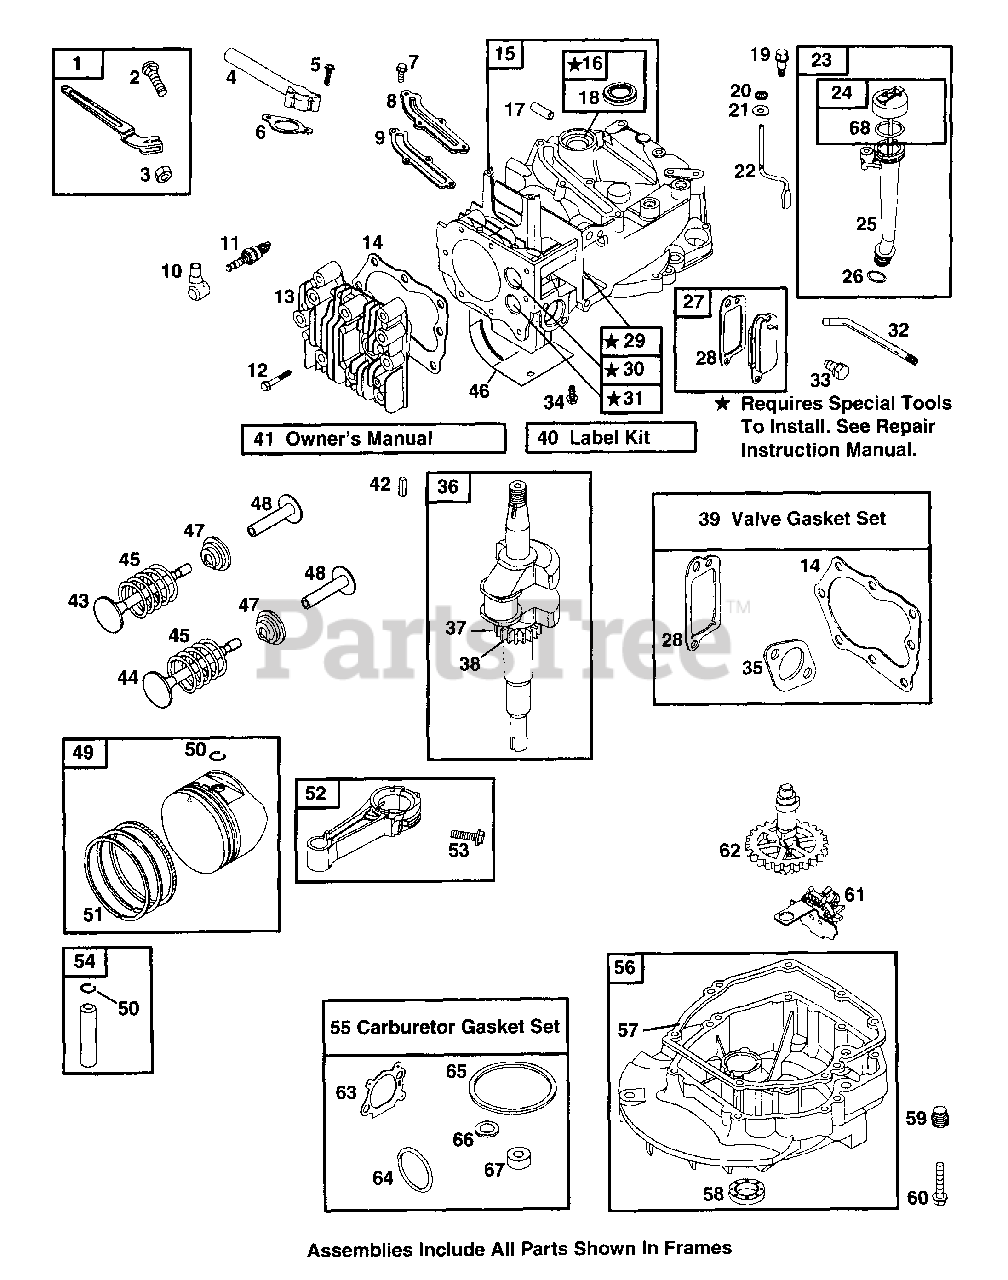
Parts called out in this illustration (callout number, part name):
1	Governor Control Lever
4	Intake Manifold
6	Intake Gasket
8	Breather Passage Cover
9	Breather Passage Gasket
10	Sparkplug Boot
12	Screw (Cylinder Head)
13	Cylinder Head
14	Cylinder Head Gasket
15	Cylinder Assembly
16	Bushing/Seal Kit
17	Locating Pin
18	Oil Seal (Magneto Side)
20	Governor Shaft Retainer
22	Governor Crank
23	Dipstick/Tube Assembly
24	Dipstick
25	Dipstick Tube
26	Dipstick Tube Seal
27	Oil Seal
28	Breather Gasket
29	Guide Bushing (Exhaust Valve)
30	Valve Seat (Intake)
31	Valve Seat (Exhaust)
32	Breather Tube
35	Exhaust Gasket
36	Crankshaft Assembly
37	Timing Key
38	Timing Gear
39	Valve Gasket Set
41	Owner's Manual
42	Flywheel Key
43	Intake Valve
44	Exhaust Valve
45	Valve Spring
46	Cylinder Shield
47	Valve Retainer
48	Valve Tappet
49	Piston Assembly (Standard)
50	Piston Pin Lock
51	Ring Set (Standard)
52	Connecting Rod (Standard)
54	Piston Pin
55	Carburetor Gasket Set
56	Engine Sump
57	Crankcase Gasket
58	Oil Seal (PTO Side)
59	Oil Drain Plug
61	Governor/Oil Slinger
63	Air Cleaner Gasket
64	O-Ring Seal (Intake Manifold)
65	Float Bowl Gasket
66	Sealing Washer
67	Choke/Throttle Dust Seal
68	Dipstick/Tube Seal
